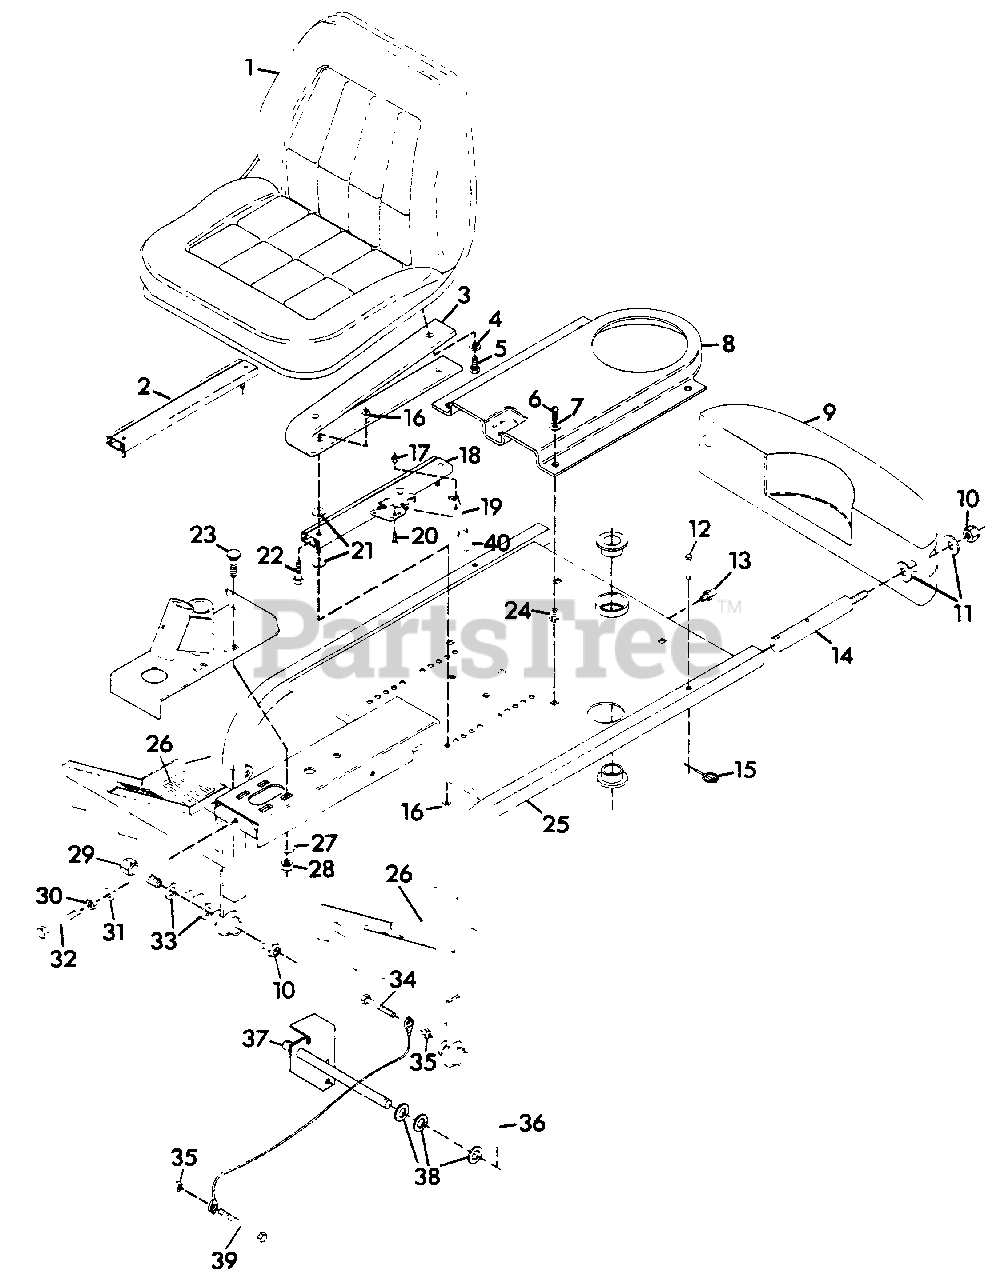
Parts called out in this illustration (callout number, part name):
1	SEAT, DELUXE
2	ADJUSTER, SEAT
3	SPRING, SEAT
4	WASHER, LOCK 5/16
5	BOLT, HEX 5/16-18X.75
6	SCREW, TAPPING 1/4-20X.625 P/HD
7	WASHER, FLAT .281X.625X.065
8	COVER, CHAIN
9	WEIGHT, PRO MASTER-60
10	NUT, LOCK 3/4-10
11	WASHER, FLAT .813X2.0X.148
12	PIN, CLEVIS 3/8X2.62
13	FITTING, LUBE 1/4-28
14	SHAFT, WEIGHT
15	PIN, KLIK
16	NUT, LOCK 5/16-18
17	NUT, LOCK 10-24
18	ADJUSTER, SEAT W/LATCH
19	HANDLE, SEAT ADJUSTER
20	SCREW, MACHINE 10-24X.625 P/HD
21	SPACER
22	BOLT, HEX 5/16-18X1.25
23	BOLT, 3/8-16X1.00 RD HD SQ NK
24	GROMMET, PLASTIC
25	WELDMENT, FRAME
26	COVER, FOOTBOARD
27	WASHER, FLAT .406X.812X.065
28	NUT, LOCK 3/8-16
29	BOLT, HEX 3/4-10X3.75
30	NUT, JAM 3/8-16 HEX
31	WASHER, LOCK 3/8 REG.
32	BOLT, HEX SPECIAL 3/8-16X3.00
33	WASHER, FLAT .812X1.469X.130
34	BOLT, HEX 5/16-24X2.25
35	NUT, LOCK 5/16-24
36	PIN, COTTER .125X1.25
37	WELDMENT, LIFT BRACKET
38	WASHER, FLAT .656X1.250X.100
39	BOLT, HEX 5/16-24X3.50
40	TIP, LEVER
NS	DECAL, PRO MASTER-60
NS	DECALS, PRO MASTER 18 HP
NS	DECALS, PRO MASTER 20 HP
NS	DECAL, GRAVELY LOGO
NS	DECAL, AMERICA
NS	DECAL, HI-SPEED
